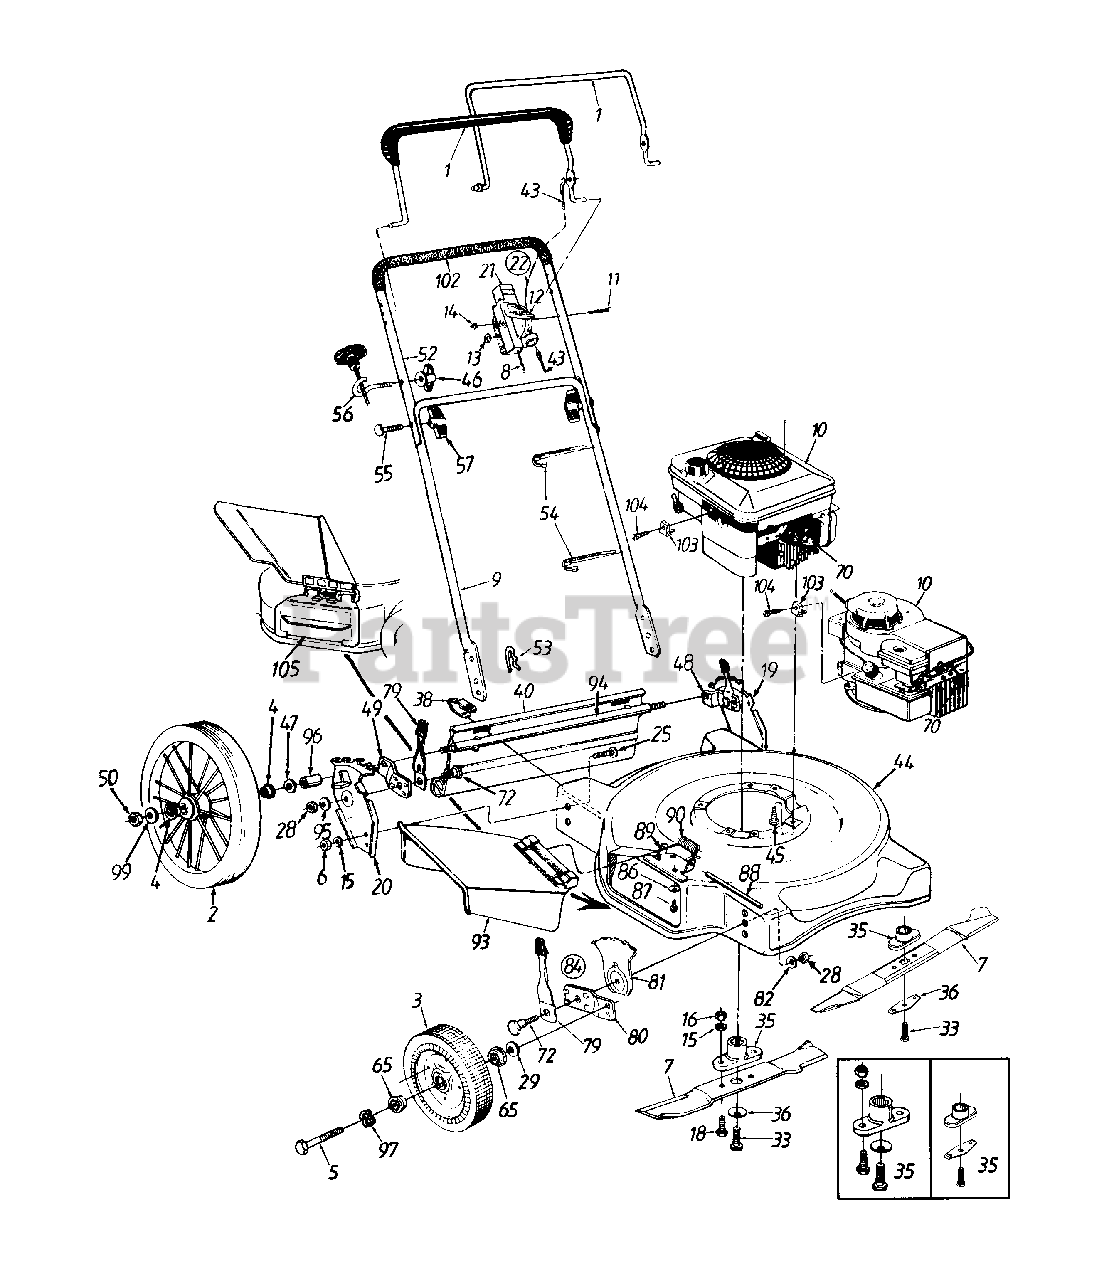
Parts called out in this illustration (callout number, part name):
2	16" Wheel Ass'y.
3	Front Wheel Ass'y.
4	Bearing 1/2" I.D.
5	Front Axle Bolt
6	Hex Nut 3/8-24 Thd. (Gr. 8)
7	22" Blade
8	Throttle Control Wire--51"
10	Engine
11	Oval C-Sunk Mach. Scr.
12	Throttle Lever
13	Spr. Wash. .66" I.D.
14	Hex L-Nut 1/4-20 Thd.
15	L-Wash. 3/8" I.D.
16	Hex Nut 3/8-24 Thd.
18	Hex Bolt 3/8-24 x 1.0" Lg.
22	Throttle Box Comp.
25	Ribbed Neck Bolt 3/8-24 x .80"
28	Hex Nut 3/8-16 Thd.
29	Bell-Wash. .400" I.D. x .88"
33	Hex Bolt 3/8-24 x 1.5" Lg.
35	Blade Adapter Kit
36	Bell-Wash. .39" I.D.
38	Hinge Clip
40	Rear Flap Ass'y.
43	Control Cable--39"
46	Handle Knob 1/4-20 Thd.
47	Wave Wash. .51" I.D.
48	Small Pivot Bar--L.H.
49	Small Pivot Bar--R.H.
50	Hex Jam Nut 3/8-16 Thd.
54	Cable Tie
55	Curved Hd. Bolt 5/16-18 x 2" L.
56	Rope Guide
57	Hand Knob
65	Bearing
70	Spark Plug Boot
72	Shoulder Bolt .50" Dia.
79	Spring Lever Ass'y. w/Knob
81	Height Adj. Plate
82	Bell-Wash. .39" I.D. x 1.38"
84	Fr. Height Adj. Ass'y. Comp. R.H.
86	Bell-Wash. .285" I.D. x .75"
87	Hex Wash. Hd. Tap Scr. 1/4-20 x .5" Lg.
88	Hinge Pin
89	Adapter Plate
90	Torsion Spring
93	Chute Deflector Ass'y. Comp.
94	Rear Axle
95	Bell-Wash. .39" I.D. x 1.13"
96	Spacer .55" I.D. x .75"
97	Wave Washer .51" I.D.
99	Fl-Wash. .406" I.D. x .81"
102	Foam Grip
103	Casing Clamp
104	Hex Wash. Hd. Tap Scr. #10-32 x .62" Lg.
105	Mulching Baffle
